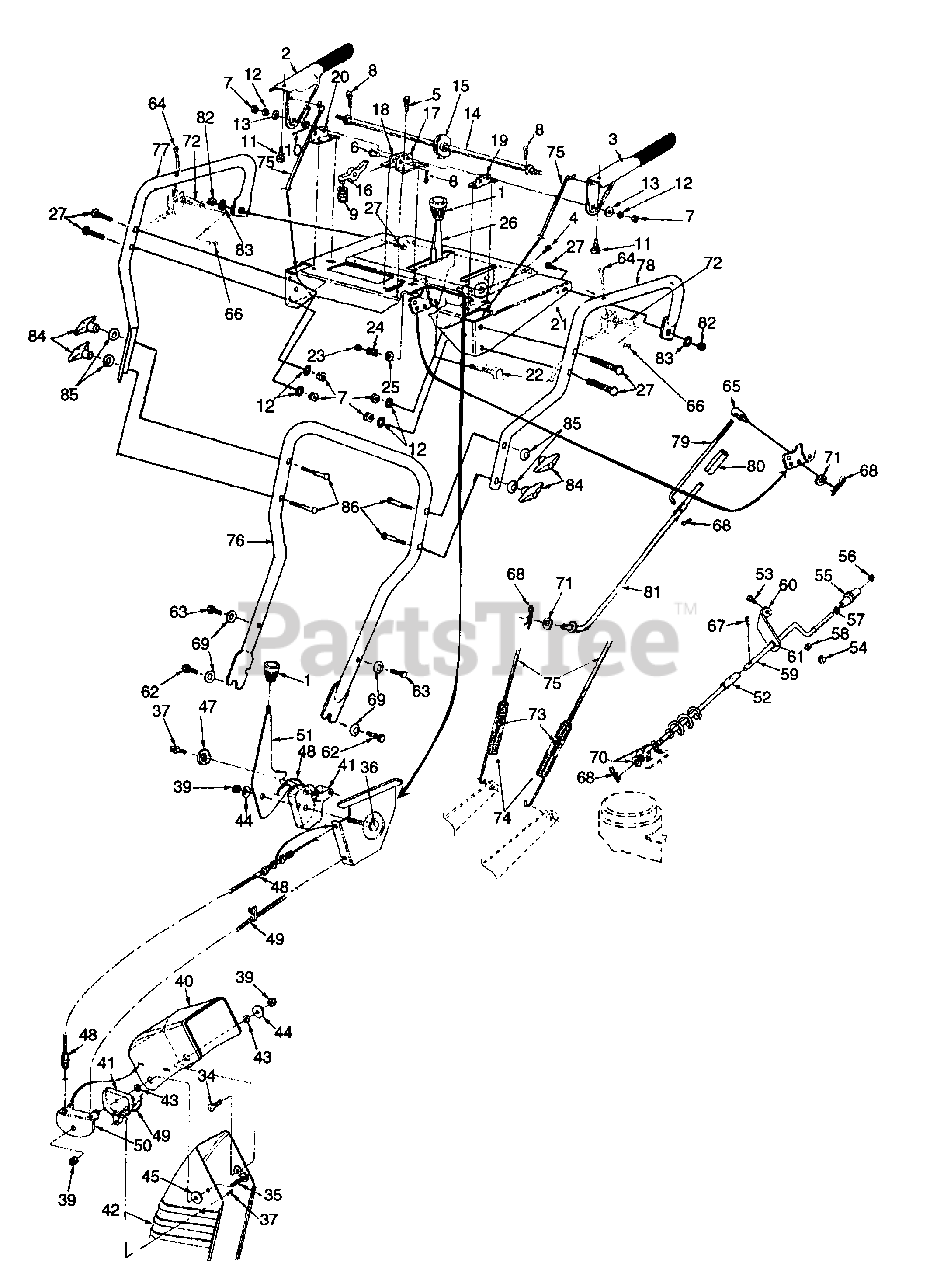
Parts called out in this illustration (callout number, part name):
1	Shift Knob
2	Engage Handle Le Blk Dip Rh
3	Engage Handle Lf Blk Dip Lh
4	Pan Head B-tapp Scr #10 x .5
5	Hwhd Sf-tap Scr 1/4-20 x 1/2 Lg.
6	Clevis Pin .31 Dia x 1.0
7	Nut Hex 5/16-18 Gd 5
8	Cot-pin 3/32 Dia x 1.0
9	Comp Spring .36 Dia x 1.0 Lg
10	Spring Torsion .44 ID
11	Rubber Bumper .63 Dia
12	Lock Washer 5/16
13	Wsher Spcl. .345 I.D. x .72 OD
14	Cam Rod
15	Clutch Lock Cam
16	Clutch Lock Pawl
17	Supt Brkt 5/8 L.H.
18	Supt Brkt 5/8 R.H.
20	Supt Brkt 3/8 R.H.
22	Scr Hex Cap 3/8-24 x 1.5 Gd 5
23	Hex Ins L-nut 3/8-24
24	Compression Spring .39 ID x .88
25	Bell Wash .40 ID x .88 OD x .06
26	Shift Handle
27	Carriage Bolt 5/16-18 x 1.75
34	Carriage Bolt 5/16-18 x 1.00
35	Carriage Bolt 5/16-18 x 1.75
36	Hex Scr 5/16-18 x 1.5
37	HWHD B Tapp Scr 1/4 x 5/8 Lg.
39	Hex Ins L-nut 5/16-18
40	6" Upper Chute Remote Tilt
41	Chute Tilt Cable Guide
42	6" Lower Chute Remote Tilt
43	Chute Pivot Spacer
44	Fl-wash .344 ID x .88 OD x .063
45	Flt Wshr .344 x 1.125 x .125
47	Contoured Washer
48	Chute Control Cable 66"
49	Chute Control Cable 66" W/clip
51	Chute Tilt Handle
52	Lower Chute Directional Control
53	Hex Scr 1/4-20 x .75 Lg Gd5
54	Hex Nut 1/4-20
55	Chute Directional Control Knob
56	Push Cap 3/8 Palnut #375011
57	Flat Washer .38 ID x .60 OD x .033
58	Bell Wash .26 ID x .75 OD x .06T
59	Upper Chute Directional Control
60	Brkt chute directional control
61	Plastic Bushing.380 ID
62	Hex Scr 3/8-16 x .75
63	Hex Scr 3/8-16 x 1.75
64	Scr Oval C/sunk #10-24 x 1.75
65	Adjustment Ferrule
66	#10-24 Flat Weld Nut
67	Internal Cot-pin 1/2 Dia
68	Inter Cot-pin 5/16 Dia
69	Bell Wash .4 ID x .88 OD x .06
70	Fl-wash .406 ID x .74 OD x .063
71	Fl-wash Sae .34 x .68 x .062
72	Trigger Ass'y Steer
73	Hex Ins L-nut 1/4-20
74	Extension Spring
75	Cable Clutch Drive
79	Upper Shift Rod 5/16 x 10.57
80	2 Pc Shift Rod Connector
81	Lower Shift Rod 3/8 x 14.75
82	Hex Nut 1/4 - 20
83	Bell Wash .26 ID x .75 OD x .06T
84	Wingnut
85	Bell Wash .345 ID x .88 OD x .060
86	Carriage Bolt 5/16 -18 x 2.5
